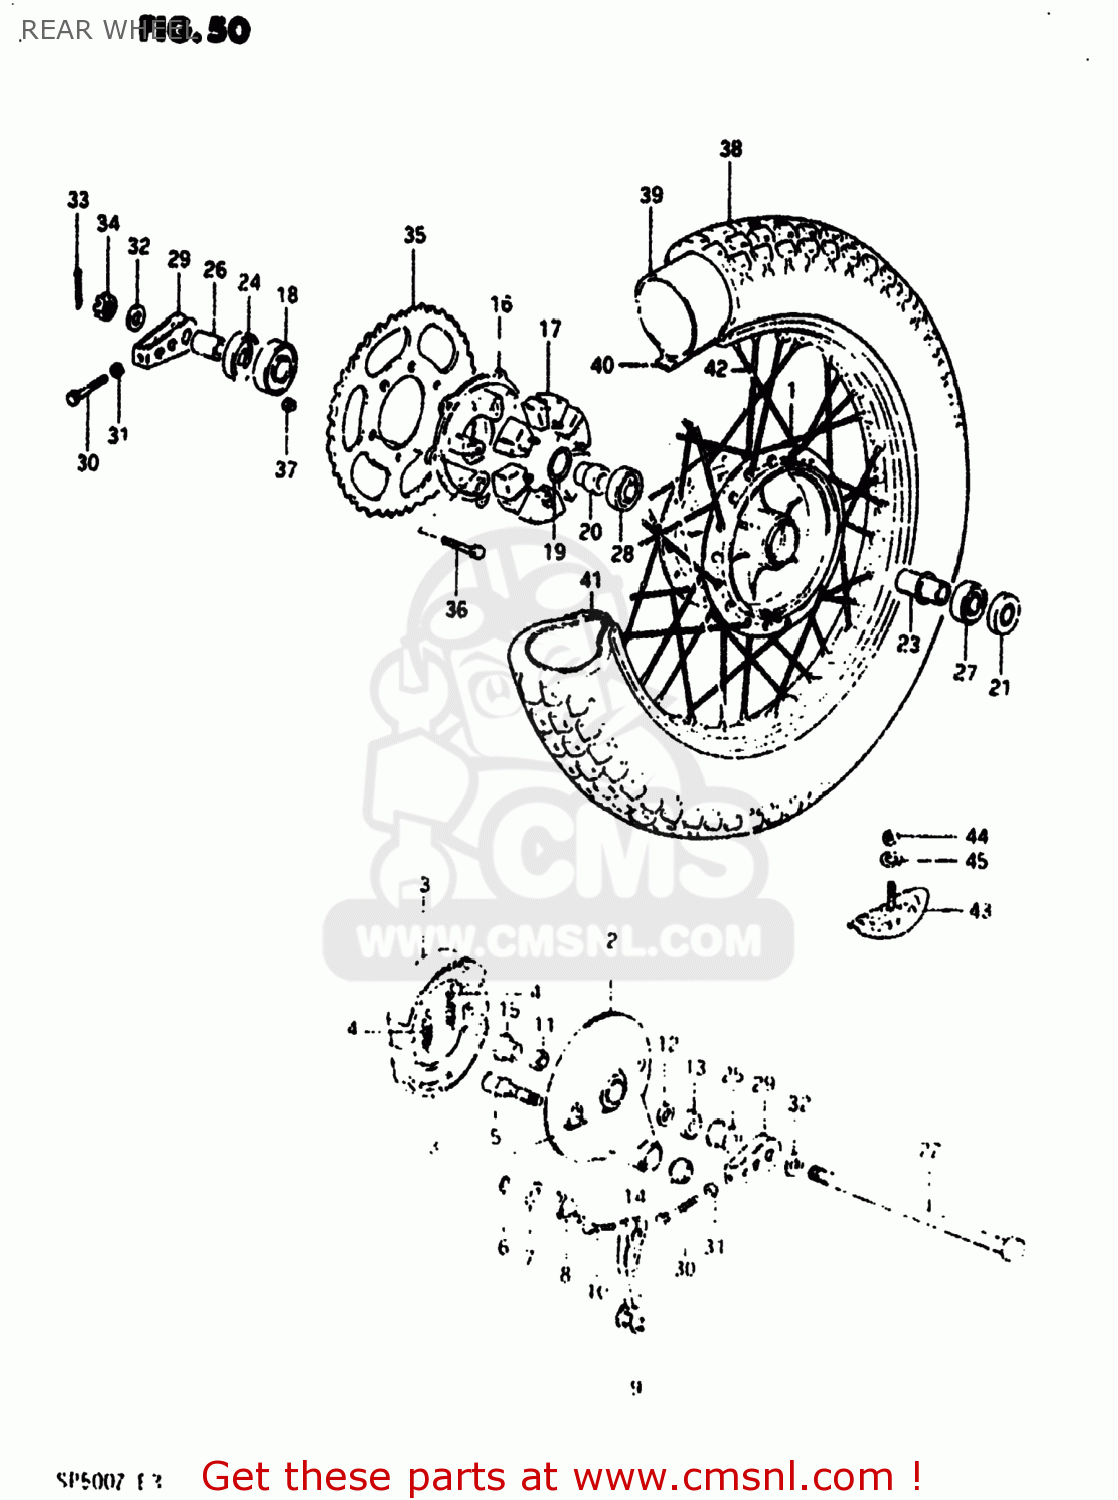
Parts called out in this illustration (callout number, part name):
1	DRUM,REAR HUB
2	PANEL,REAR HUB
3	SHOE,BRAKE (MCA)
4	SPRING
5	CAM,FRONT BRAKE
6	O-RING,BOSS
7	WASHER (15X24X1.6)
8	SPRING
9	LEVER,REAR BRAKE CAM
10	BOLT
11	BEARING(24X31X28)
12	WASHER
13	CVR,RR BRAKE AHR PNL DUST SEAL
14	SPHERICAL BRNG,TORQUE LINK
15	SPACER,REAR HUB PANEL
16	DRUM,REAR SPROCKET MOUNT
17	ABSORBER,RR HUB SHOCK
18	BEARING
19	O-RING
20	SPACER,REAR SPROCKET DRUM
21	OIL SEAL
22	AXLE,REAR
23	SPACER,REAR HUB BEARING
24	SEAL,OIL(30.5X52X8)
25	SPACER,REAR AXLE,RIGHT
26	SPACER(17X30.5X16.3)
27	BEARING
28	BEARING
29	ADJUSTER,CHAIN
30	BOLT
31	NUT
32	WASHER (17X30X3.2)
33	PIN,COTTER
34	NUT
35	SPROCKET,REAR (NT:46)
36	BOLT
37	NUT
38	TIRE
39	TUBE,INNER
40	PROTECTOR,WHEEL,INNER
41	RIM,REAR WHEEL
42	SPOKE ASSY,RR WHEEL
43	STOPPER,BEAD
44	NUT
45	WASHER
